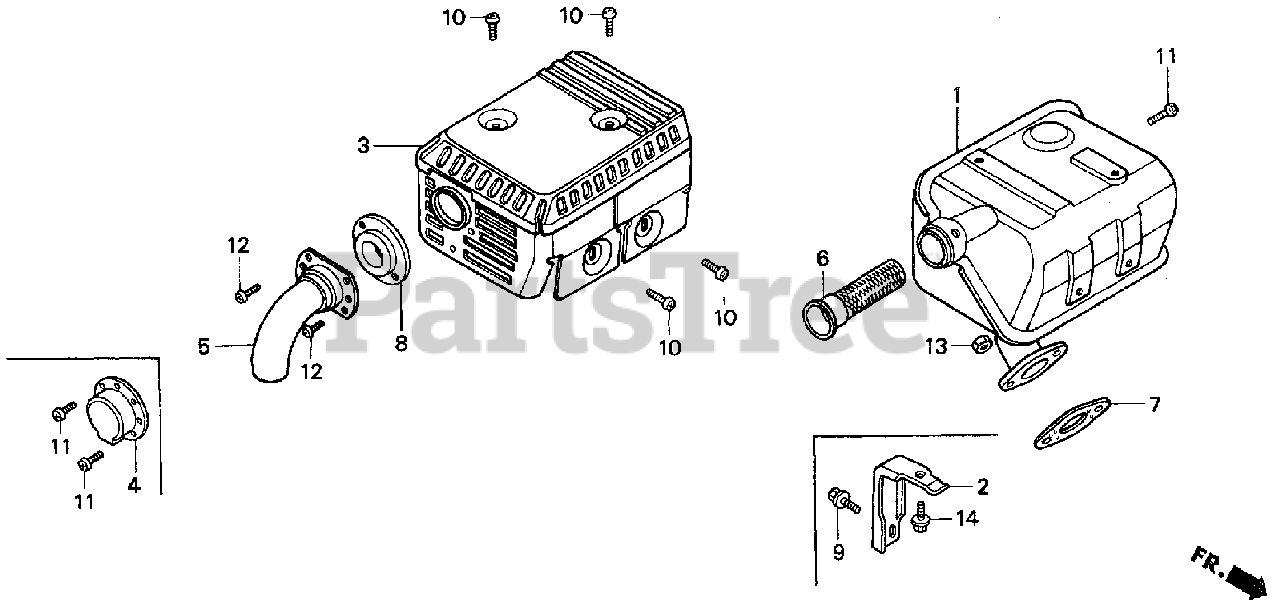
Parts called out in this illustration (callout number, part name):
1	MUFFLER
3	PROTECTOR, MUFFLER
6	ARRESTER, SPARK
7	GASKET, MUFFLER
10	SCREW, TAPPING (5X8)
11	SCREW, TAPPING (4X6)
13	NUT, HEX. (8MM)
